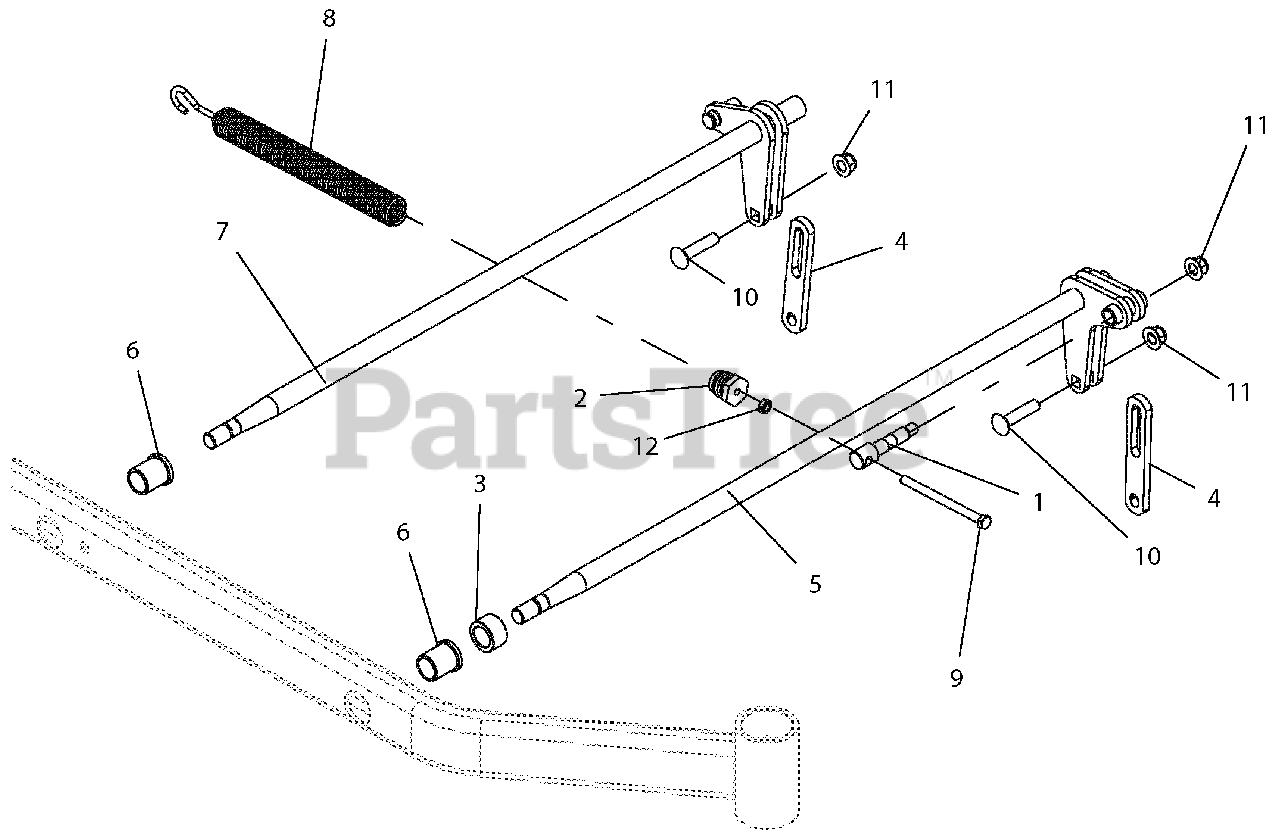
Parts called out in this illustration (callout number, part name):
1	TRUNION, SPRG
2	PLUG, SPRG
3	SPACER, 1.500 X 1.000 X .880
4	LINK, DECK LIFT - LONG
5	WLDMT, FRONT LH DECK LIFT ARM-BLACK
6	BSHG-FLG 1.00X1.25X1.5X1.5
7	WLDMT, REAR LH DECK LIFT ARM-BLACK
8	SPRG, DECK LIFT
9	BLT-HEX .38-16X5.00 GR5 YWZC
10	BLT-RDHDSQNK .50-13X2.25 G5 Y
11	NUT-LK-NYL-FLG .50-13 YWZC
12	NUT, JAM .375-16 YWZC
